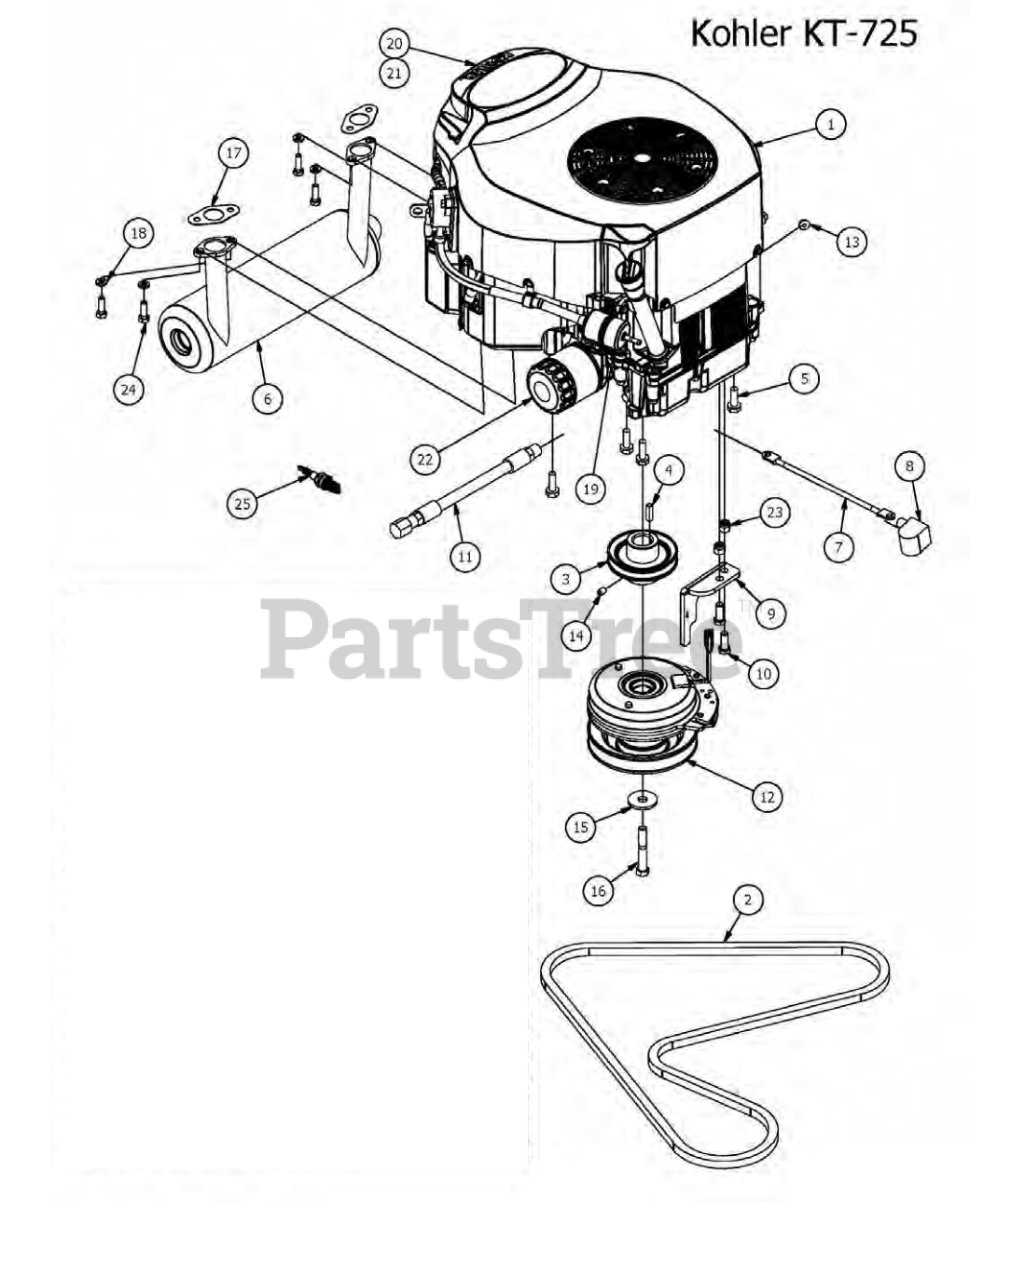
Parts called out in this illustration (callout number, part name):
1	Kohler KT-725
3	3-3/4" Motor Pulley
4	1/4" x 1" Key
5	3/8 x 1 1/8 bolt
6	2014 MZ Muffler-725cc Kohler
7	Ground Cable
8	Black Boot For Ground Cable
9	Warner Clutch A-R Bracket
10	3/8" x 1" Hex Bolt
11	Oil drain Hose
12	Clutch 2015 Magnum/MZ
13	1/4-20 Hex Flange Nuts Zinc w/Serrations
14	3/8" Set Screw
15	1/2 Belleville Washer
16	7/16" x 4" Fine Thread Bolt
17	Exhaust Gasket
18	5/16" Lock Washer
19	Universal Fuel Filter
20	KT-725 & KT-740 Precleaner
21	KT-725 & KT-740 Air Elemet
22	KT-725 & KT-740 Oil Filter
23	3/8 Nylock Nut
24	5/16" x 1" Bolt
25	Spark Plug
